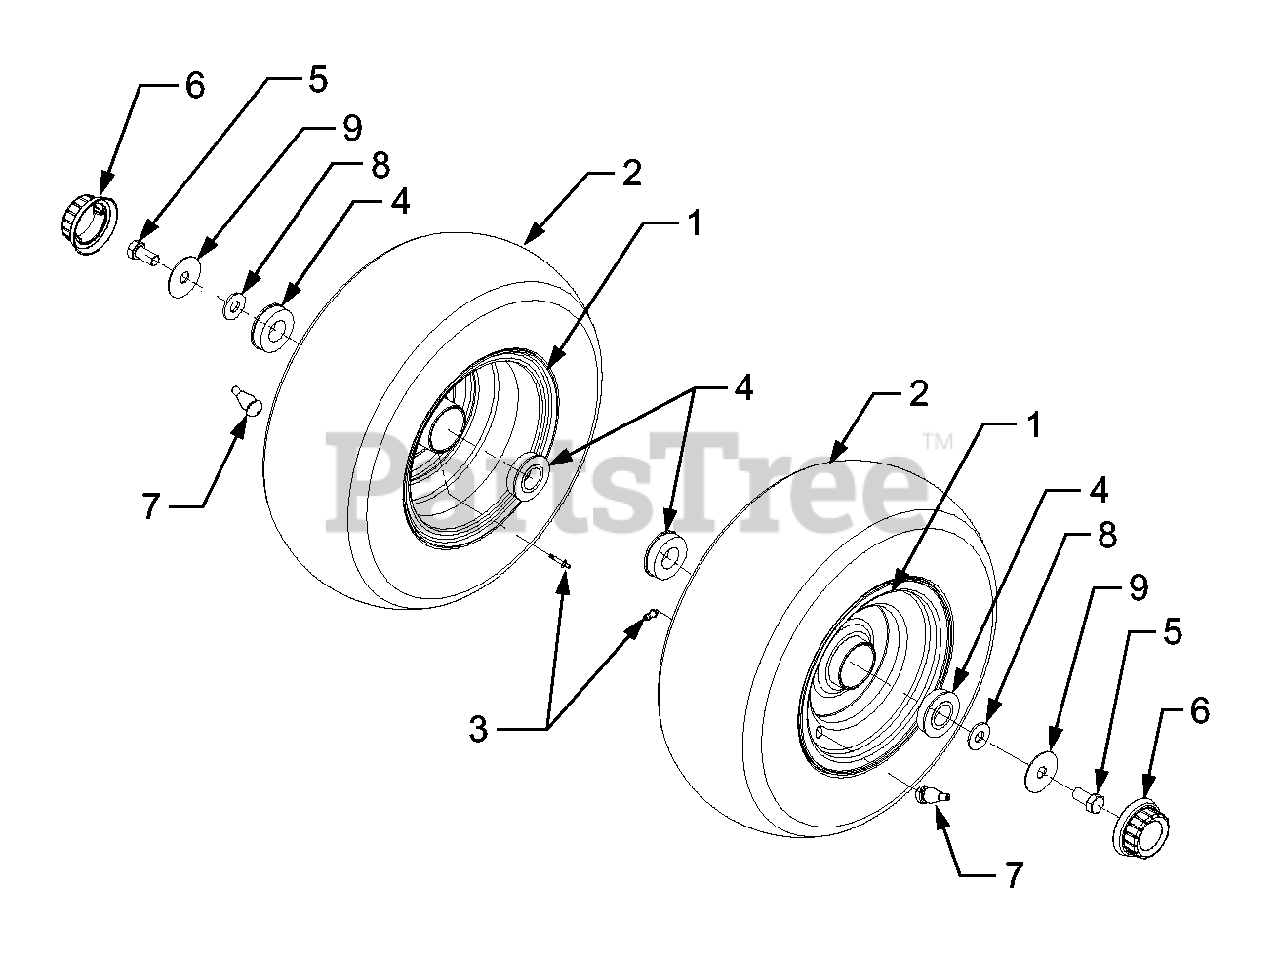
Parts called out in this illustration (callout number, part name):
1	Rim Assembly, Wheel
2	Tire, Turf, 16 x 6.5 x 8.0
3	Lube Fitting
4	Bearing, Ball
5	Screw, Hex Cap, 1/2-13 x 1.0 GR5
6	Hubcap
7	Valve, Tubeless Air
8	Washer, Flat, .531 x 1.25 x .1
9	Washer, Flat, .535 x 1.92 x .060
